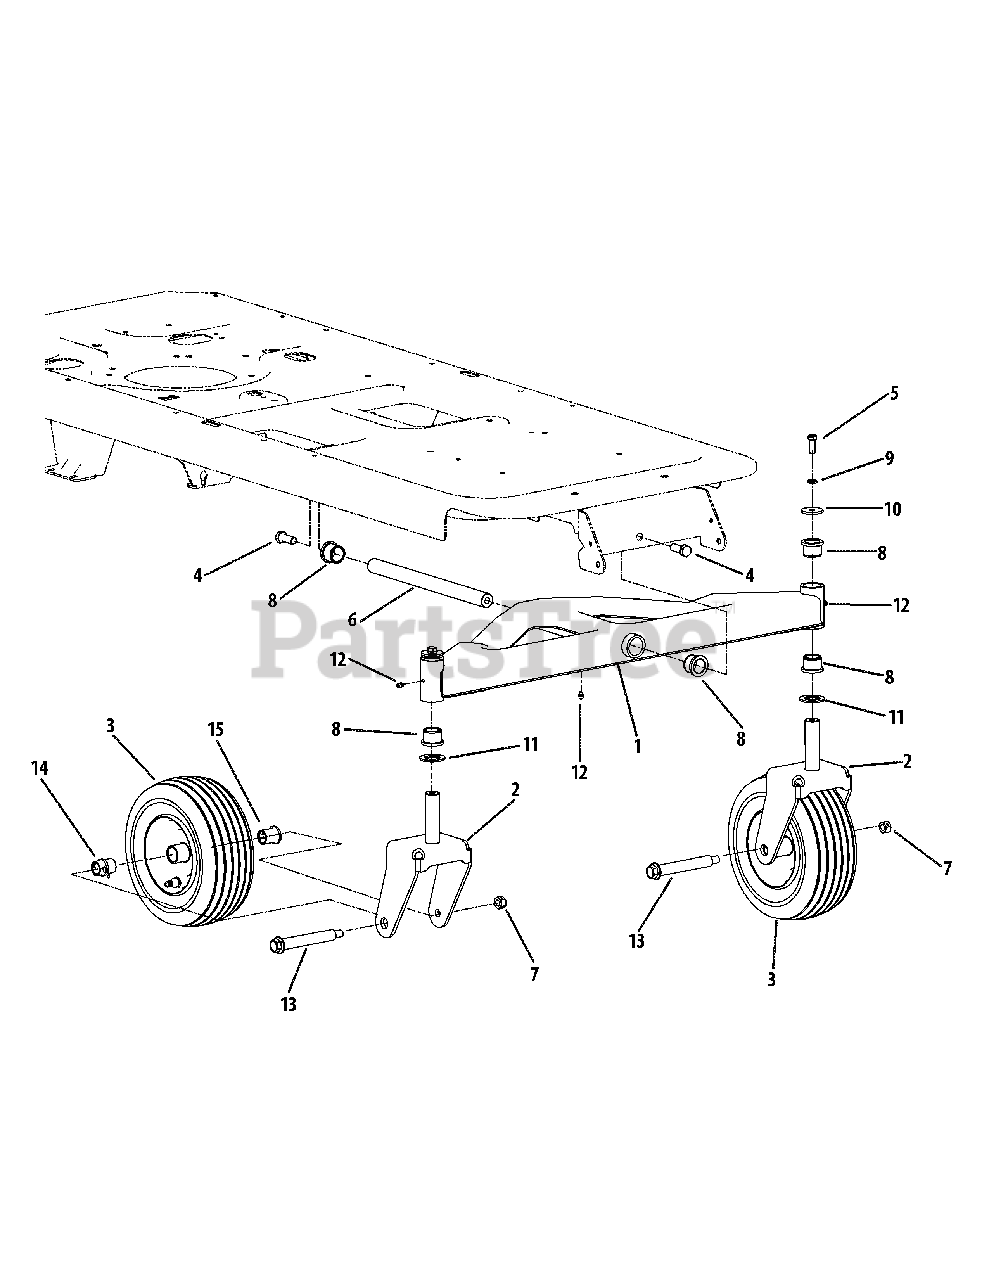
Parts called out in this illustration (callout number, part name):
3	Wheel Assembly, 11.0 x 4.0 x 5.0
4	Hex Lock Screw,1/2-13 x 1.25
5	Hex Cap Screw, 3/8 -16 x 1.0
6	Axle Shaft
7	Hex Lock Nut, 1/2-13
8	Flange Bearing, 1.0 x 1.246
9	Lock Washer, 3/8
10	Flat Washer, .39 x 1.5 x .134
11	Flat Washer, 1.0 x 1.75 x .107
12	Lube Fitting, 3/16 Drive
13	Shoulder Screw, .75 x 4.75 x 7/16-14
14	Flange Bearing, .76 x 1.0 x 1.2
15	Flange Bearing, .76 ID w/Lube Ftg.
